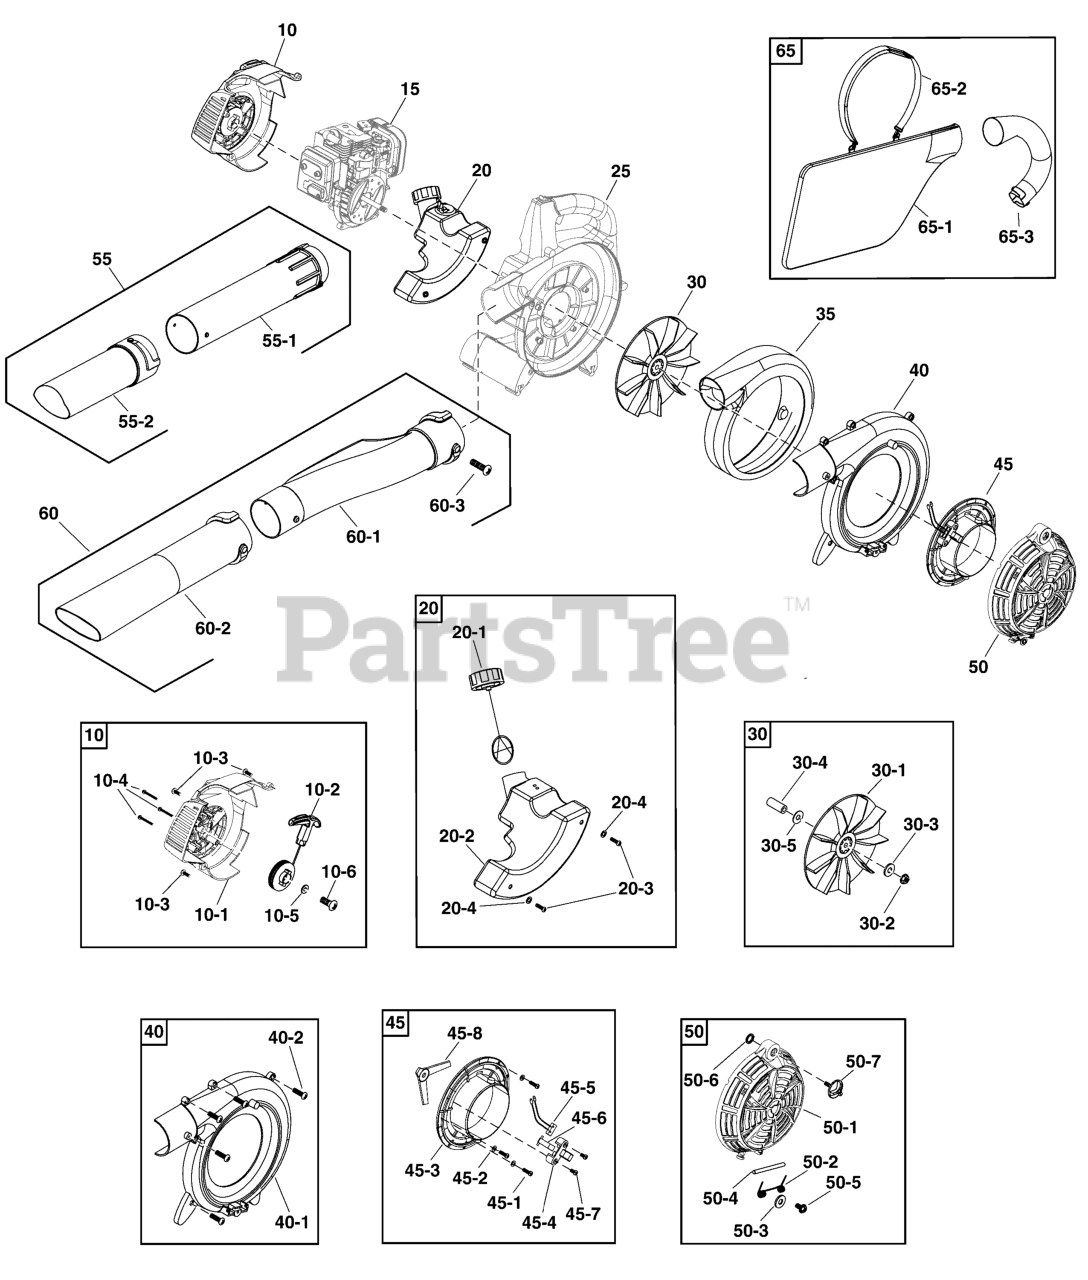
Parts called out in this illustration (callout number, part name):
10	FAN COVER ASSEMBLY
10-1	COWL, Engine
10-2	STARTER PULLEY ASSEMBLY
10-5	WASHER
20	FUEL TANK ASSEMBLY
20-1	FUEL CAP
20-2	TANK, Fuel
20-4	WASHER, 5.2 ID x 9.8 OD
25	INVOLUTE CHASSIS ASSEMBLY
30	IMPELLER ASSEMBLY
30-1	IMPELLER
30-4	SPACER
35	INNER INVOLUTE LINER ASSEMBLY
40	BLOWER HOUSING ASSEMBLY, Rear
40-1	HOUSING, Blower
45	SAFETY WIRING ASSEMBLY
45-3	COVER, Connect
45-4	COVER, Safety
45-5	SAFETY SWITCH
45-6	CONNECTOR, Button
45-8	BLADE, Mulching
50	FAN COVER ASSEMBLY
50-1	COVER, Fan
50-2	SPRING, Fan Cover
50-4	PIVOT SHAFT, Fan Cover
50-6	O-RING
50-7	KNOB, Air Filter
55	MULCHING INTAKE ASSEMBLY
55-1	INTAKE, Upper
55-2	INTAKE, Lower
60	TUBE ASSEMBLY, Blower Outlet
60-1	TUBE, Upper
60-2	TUBE, Lower
65	MULCH BAG ASSEMBLY, Single Pack
65-1	MULCH BAG
65-2	HARNESS
65-3	TUBE
